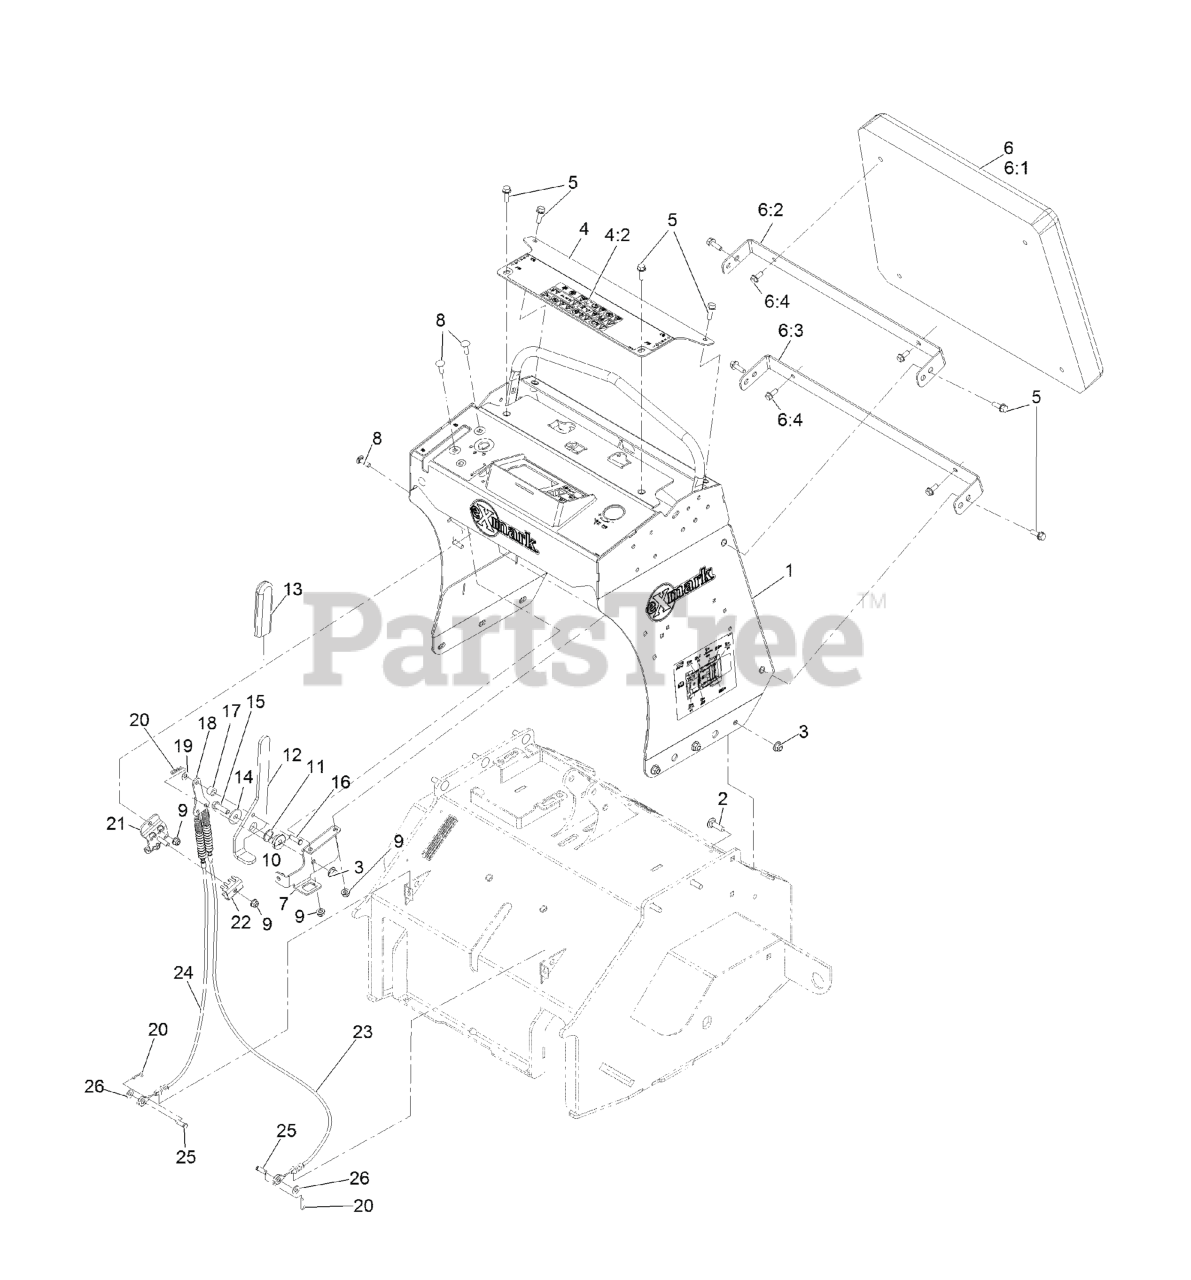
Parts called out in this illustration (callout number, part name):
1	CONTROL TOWER ASM
2	BOLT-CARR
3	NUT-HF, NI
4	CONTROL PANEL ASM
4:2	DECAL-WARNING
5	SCREW-HHF
6	Cushion ASM
6:1	CUSHION-GREY
6:2	BRACKET-PAD, UPPER
6:3	BRACKET-PAD, LOWER
6:4	SCREW-HHF
7	BRACKET-PIVOT, BRAKE
8	SCREW-CARR
9	NUT-HF, NI
10	PIVOT-FLANGE
11	WASHER-WAVE
12	HANDLE-BRAKE
13	GRIP-LEVER
14	WASHER
15	SCREW-HH
16	Pin-Yoke
17	Bushing
18	Yoke-Cable
19	SPACER-NYLON
21	Mount-Cable, Brake
22	Clamp-Cable
23	CABLE-BRAKE, LH
24	CABLE-BRAKE, RH
25	PIN-CLEVIS
26	WASHER-PLAIN
